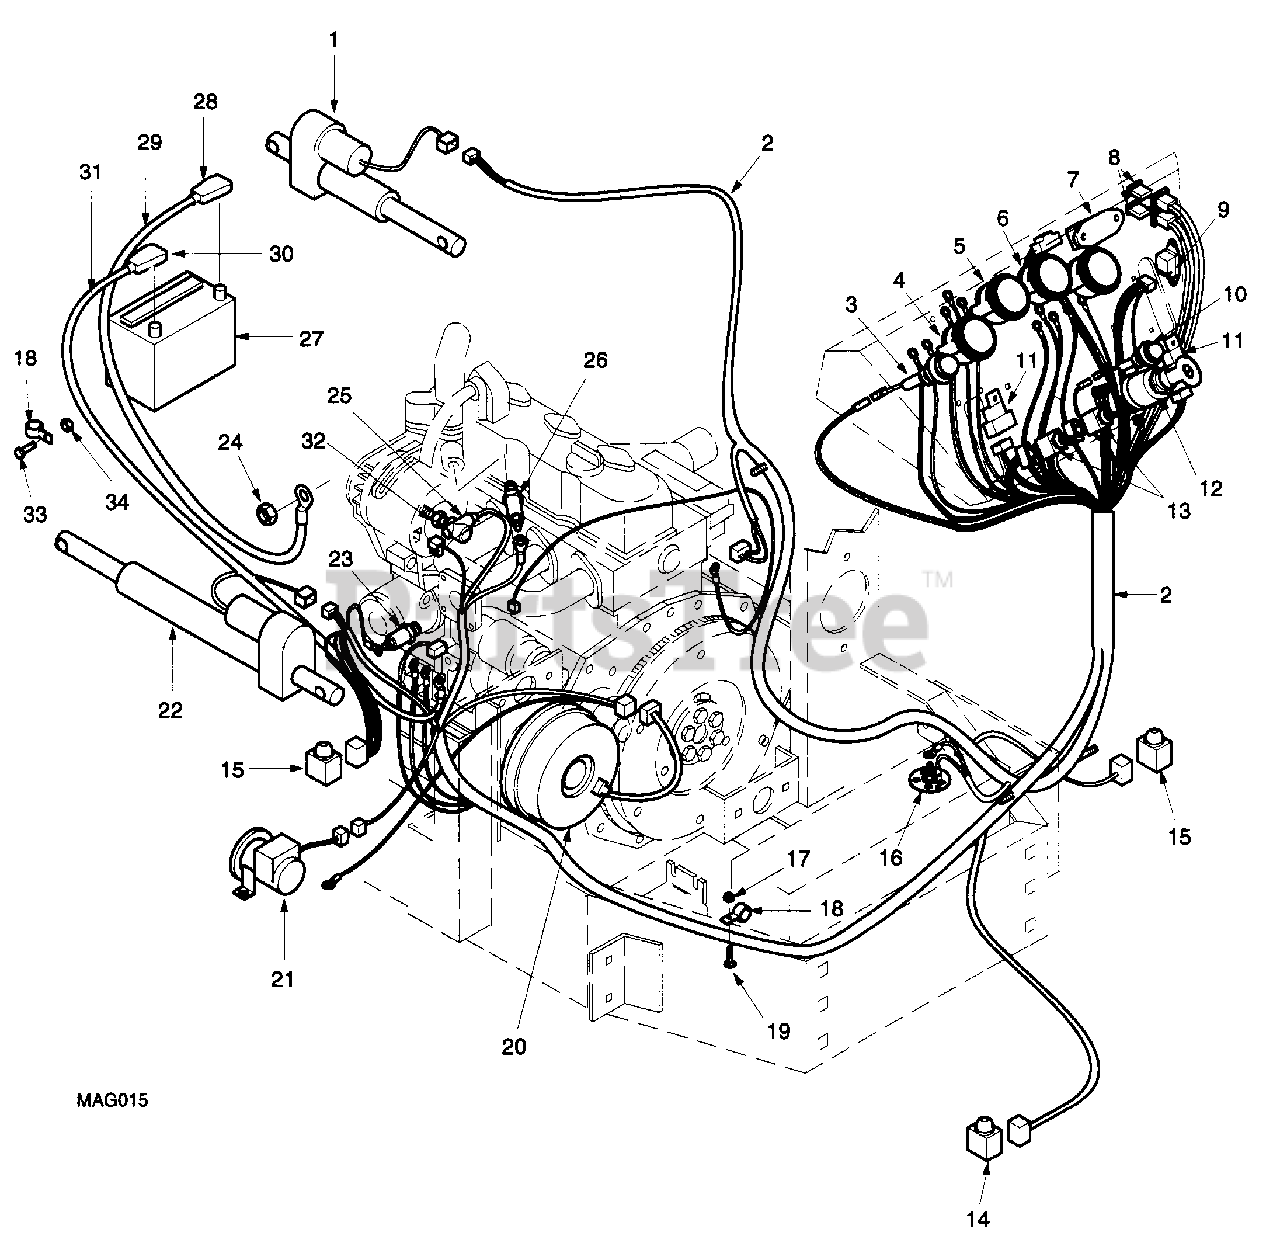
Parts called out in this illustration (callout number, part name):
1	ACTUATOR, CUTTING HEIGHT
2	WIRE HARNESS
3	INDICATOR LIGHT, OIL PRESSURE
4	HOURMETER
5	GAUGE, WATER TEMPERATURE
6	GAUGE, FUEL LEVEL
7	TIMER, DELAY CIRCUIT
8	FUSE, 30 AMP
9	TIMER, GLOW PLUG
10	INDICATOR LIGHT, GLOW PLUG
11	RELAY, SYNCHONIZE START & CLUTCH KIT CIRCUIT
12	SWITCH, IGNITION
13	SWITCH, DECK LIFT AND CUTTING HEIGHT
14	SWITCH, SAFETY - PARKING BRAKE
15	SWITCH, FOOT PEDAL & CUTTER BRAKE INTERLOCKS
16	SENDER, FUEL(INCLUDES GASKET AND SCREWS)
17	HEX LOCKNUT, ELASTIC STOP, 5/16-18
19	CARRIAGE BOLT, 5/16-18 X 3/4
20	ELECTRIC CLUTCH
21	FUEL PUMP, ELECTRIC
22	ACTUATOR, DECK LIFT
23	SENDER, OIL PRESSURE
24	HEX NUT, M8- 1.25
25	CAP, ALTERNATOR TERMINAL
26	SENDER, WATER TEMPERATURE
27	BATTERY
28	CAP, BATTERY TERMINAL - BLACK
29	BATTERY CABLE, BLACK
30	CAP, BATTERY TERMINAL - RED
31	BATTERY CABLE, RED
32	HEX NUT, M6 - 1.00
33	SERR. FL. HEX HEAD CAPSCREW, 5/16-18 X 3/4
34	SERR. FL. HEX NUT, 5/16-18
